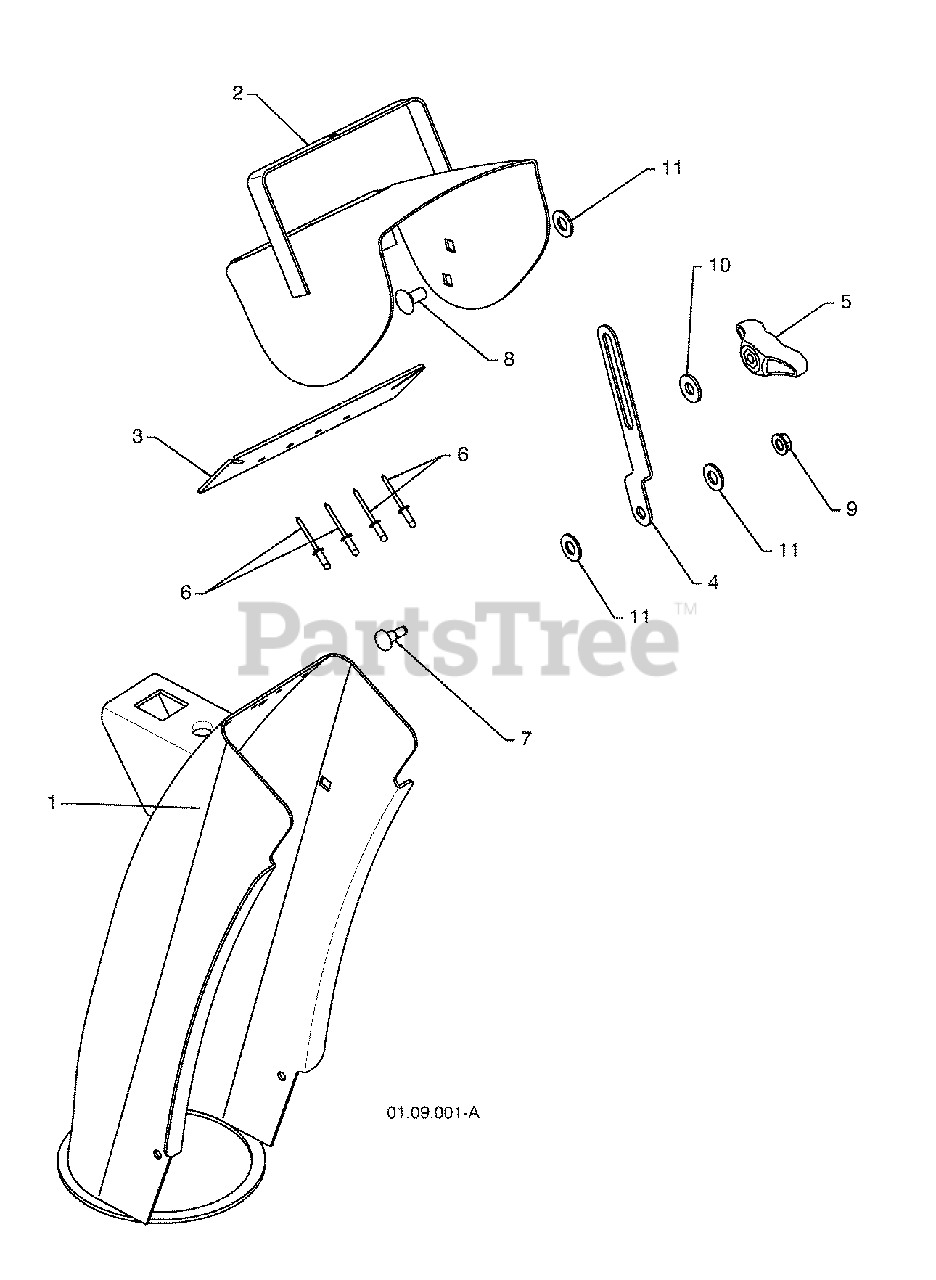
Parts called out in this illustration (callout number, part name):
1	CHUTE WELDMENT
2	DEFLECTOR WELDMENT
3	DEFLECTOR SEAL
4	STRAP
5	KNOB BLACK
7	SHOULDER BOLT 1/4-20 X .704
8	CARRIAGE BOLT 5/16-18 X .625
9	NUT 1/4-20
11	PLASTIC WASHER
